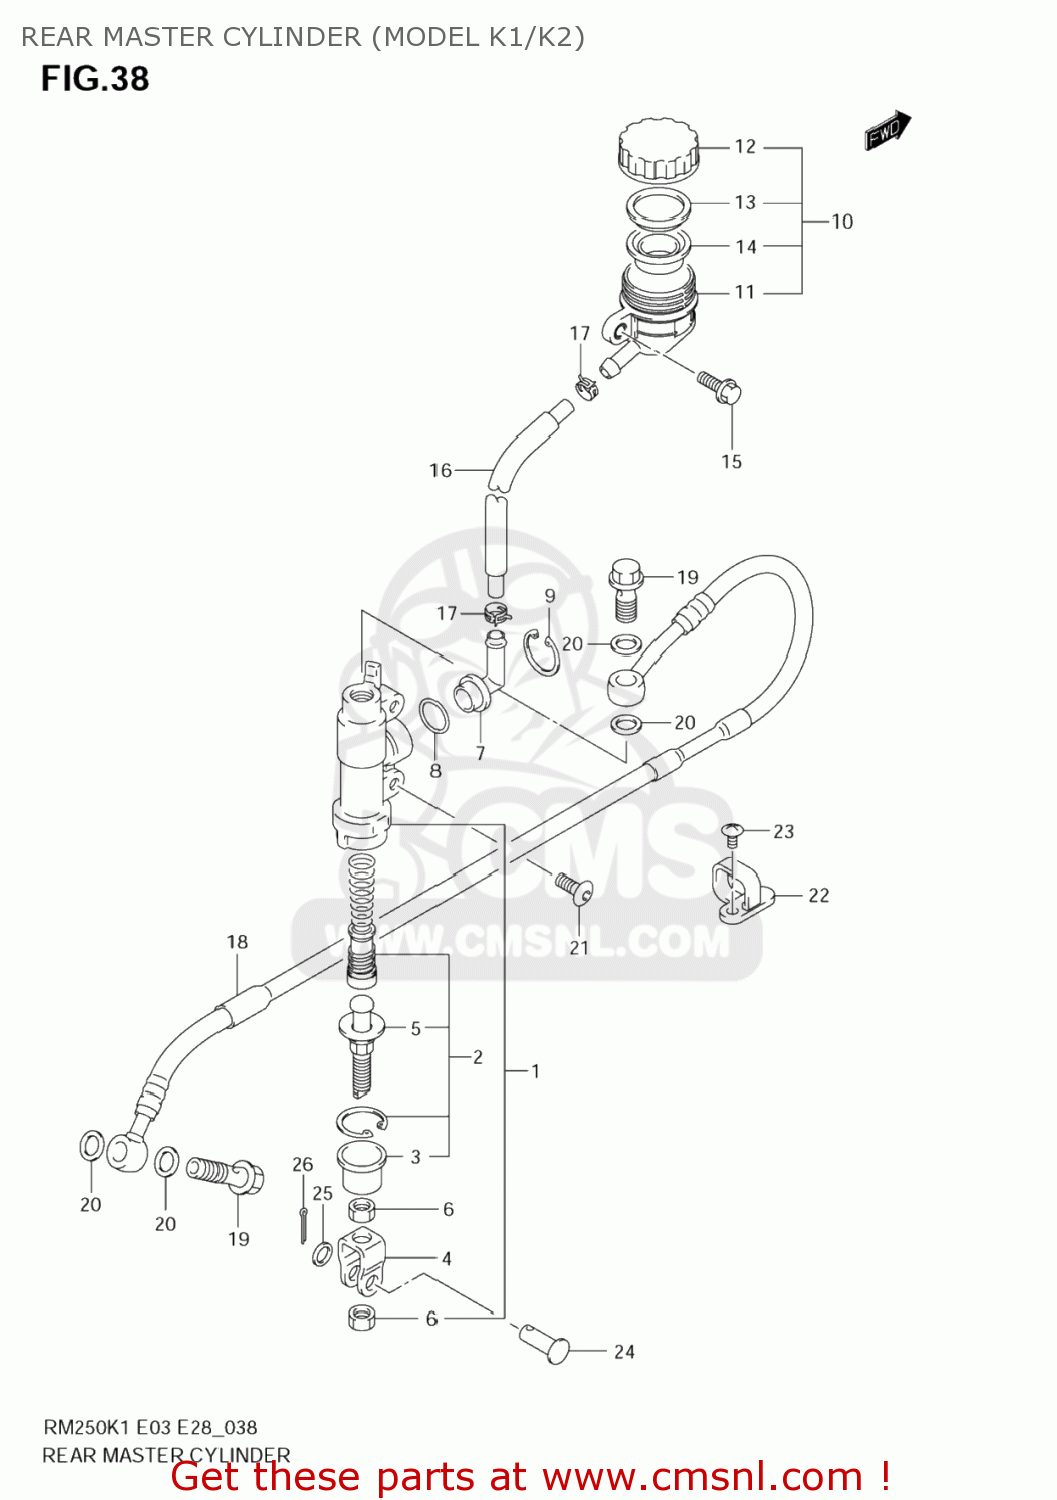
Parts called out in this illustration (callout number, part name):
1	CYLINDER ASSY,RR MASTER
2	PISTON/CUP SET
3	BOOT
4	YOKE
5	ROD,PUSH
6	NUT
7	CONNECTOR
8	O RING
9	CIRCLIP
10	TANK ASSY,RR BRAKE RESERVOIR
11	TANK,RESERVOIR
12	CAP
13	PLATE
14	DIAPHRAGM
15	BOLT(6X12)
16	HOSE
17	CLAMP,RESERVOIR HOSE
18	HOSE COMP,REAR
19	BOLT UNION
20	WASHER(10X15X1.5)
21	SCREW(6X16)
22	GUIDE,RR BRAKE
23	SCREW
24	PIN(8X20)
25	WASHER (8.5X14X1.6)
26	PIN
